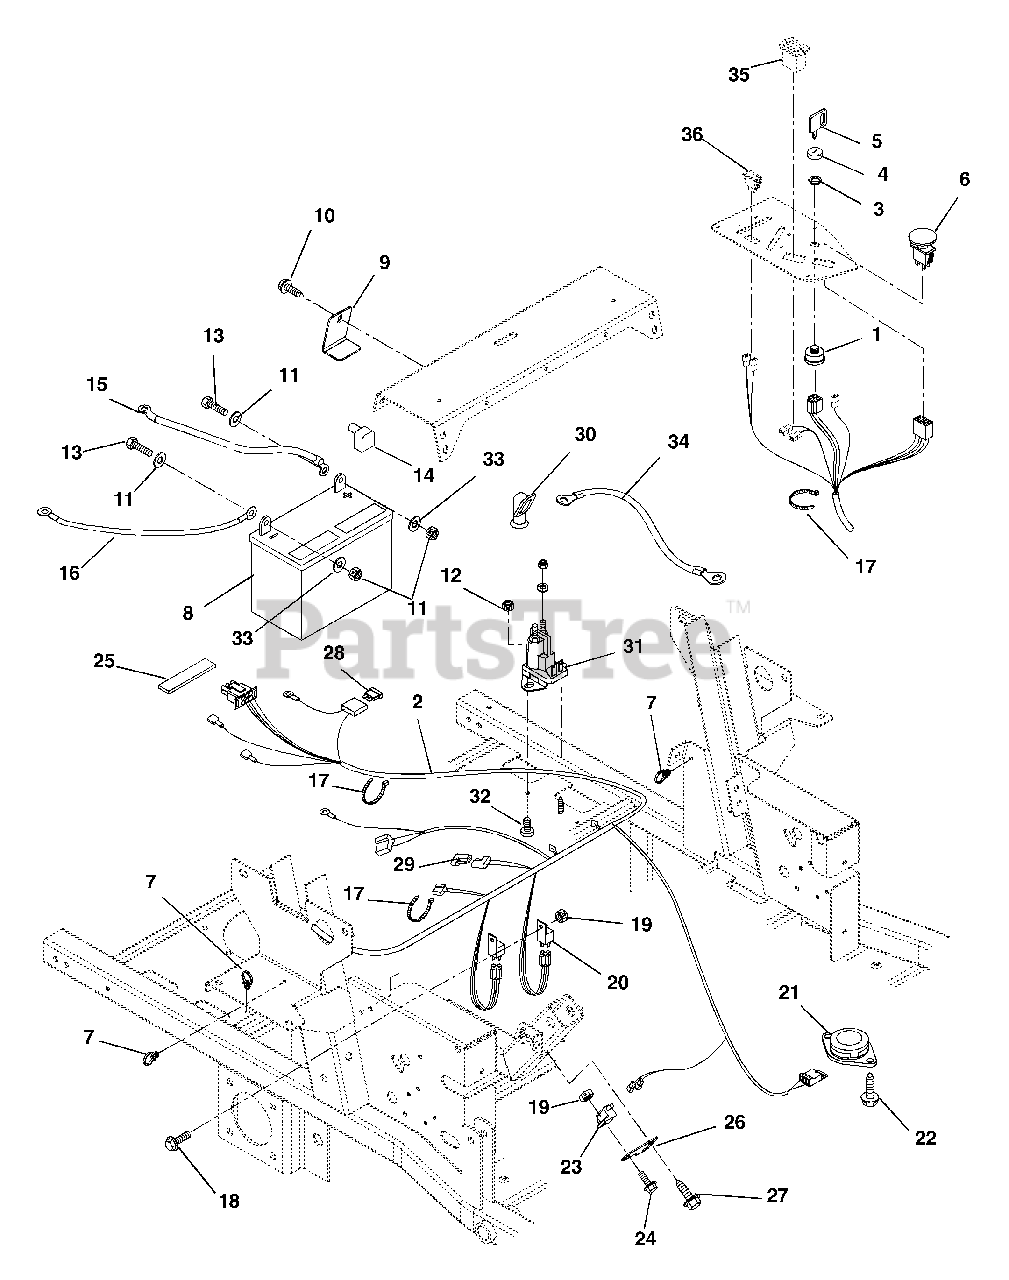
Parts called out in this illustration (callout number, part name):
1	Key Switch
2	Harness, Z 6-Pin Wiring
3	Nut-Panel .562-24
4	Cap-Ignition Switch
5	Keywith Cap
6	Switch-Clutch With Retainer Ring
7	Tube Clip .75
8	Battery with Tube
9	Clamp, Battery Hold Down
10	Screw-Tapping .25-20 x .50 Hex Washer Head
11	Washer-Flat-Steel .281 x .620 x .065
12	Nut-Hex .25-20
13	Bolt-Hex .25-20 x .75 Grade 5
14	Insulator
15	Positive Cable 22"
16	Ground Cable
17	Cable Tie
18	Screw-Machine 10-24 x .50 Hex Washer Head
19	Nut-Locking-Nylon 10-24 With Insert
20	Relay
21	Seat Switch
22	Screw-Tapping 12-24 x .50 Hex Washer Head
23	Switch-Single Pole
24	Screw-Machine 10-24 x .75 Hex Washer Head
25	Pad-Battery
26	Plate-Switch
27	Screw-Tapping .38-16 x .50 Hex Washer Head
28	Fuse, 30 Amp
29	Molded Diode Plug-Black 1-Amp
30	Insulator, Boot
31	Solenoid
32	Bolt-Hex .25-20 x .50 Grade 5
33	Washer-Locking .25 x .062
34	Starter Cable 6.75"
35	Hour Meter
36	Light-Indicator
